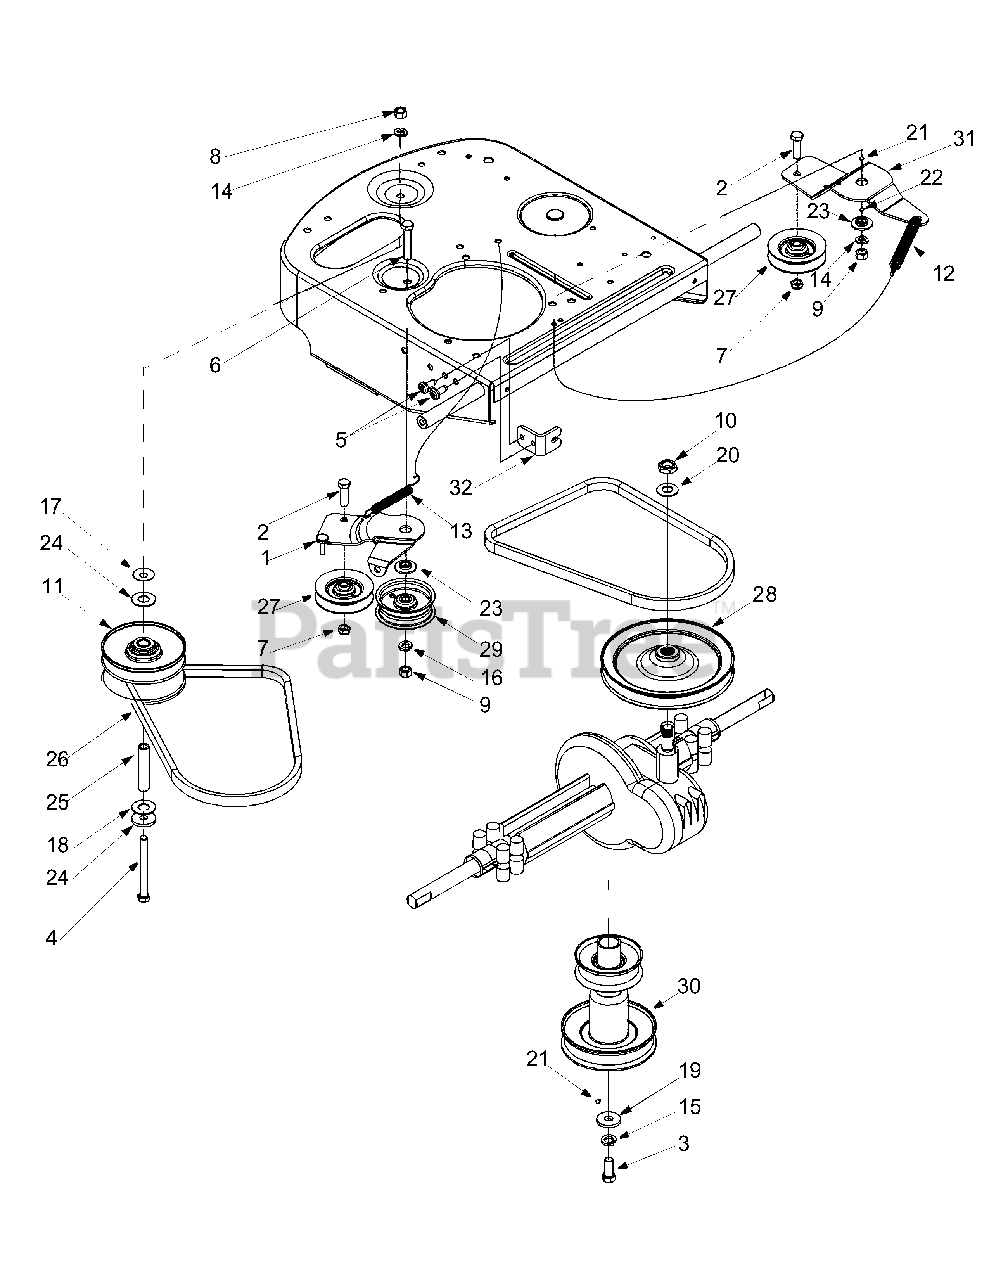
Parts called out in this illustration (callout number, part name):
1	Idler Bracket Assembly
2	Hex Screw (Special)
3	Hex Screw 7/16-20 x 1.0"
4	Hex Screw 3/8-24 x 3.75"
5	TT Screw
6	Hex Screw 3/8-16 x 2.0"
7	Jam Lock Nut
8	Hex Nut 3/8-24
9	Hex Nut 3/8-16
10	Jam Nut 9/16-18
11	Variable Speed Pulley Assembly
12	Extension Spring
13	Extension Spring
14	Lock Washer
15	Lock Washer
16	Lock Washer 3/8
17	Bell Washer
18	Flat Washer
19	Flat Washer
20	Beleville Washer
21	Grease
22	Grease: Alvania(TM)
23	Shoulder Spacer
24	Thrust Bearing
25	Slv. Spacer
26	V-Belt
27	Idler Pulley
28	Transmission Pulley
29	Flat Idler Pulley
30	Engine Pulley
31	Idler Bracket
